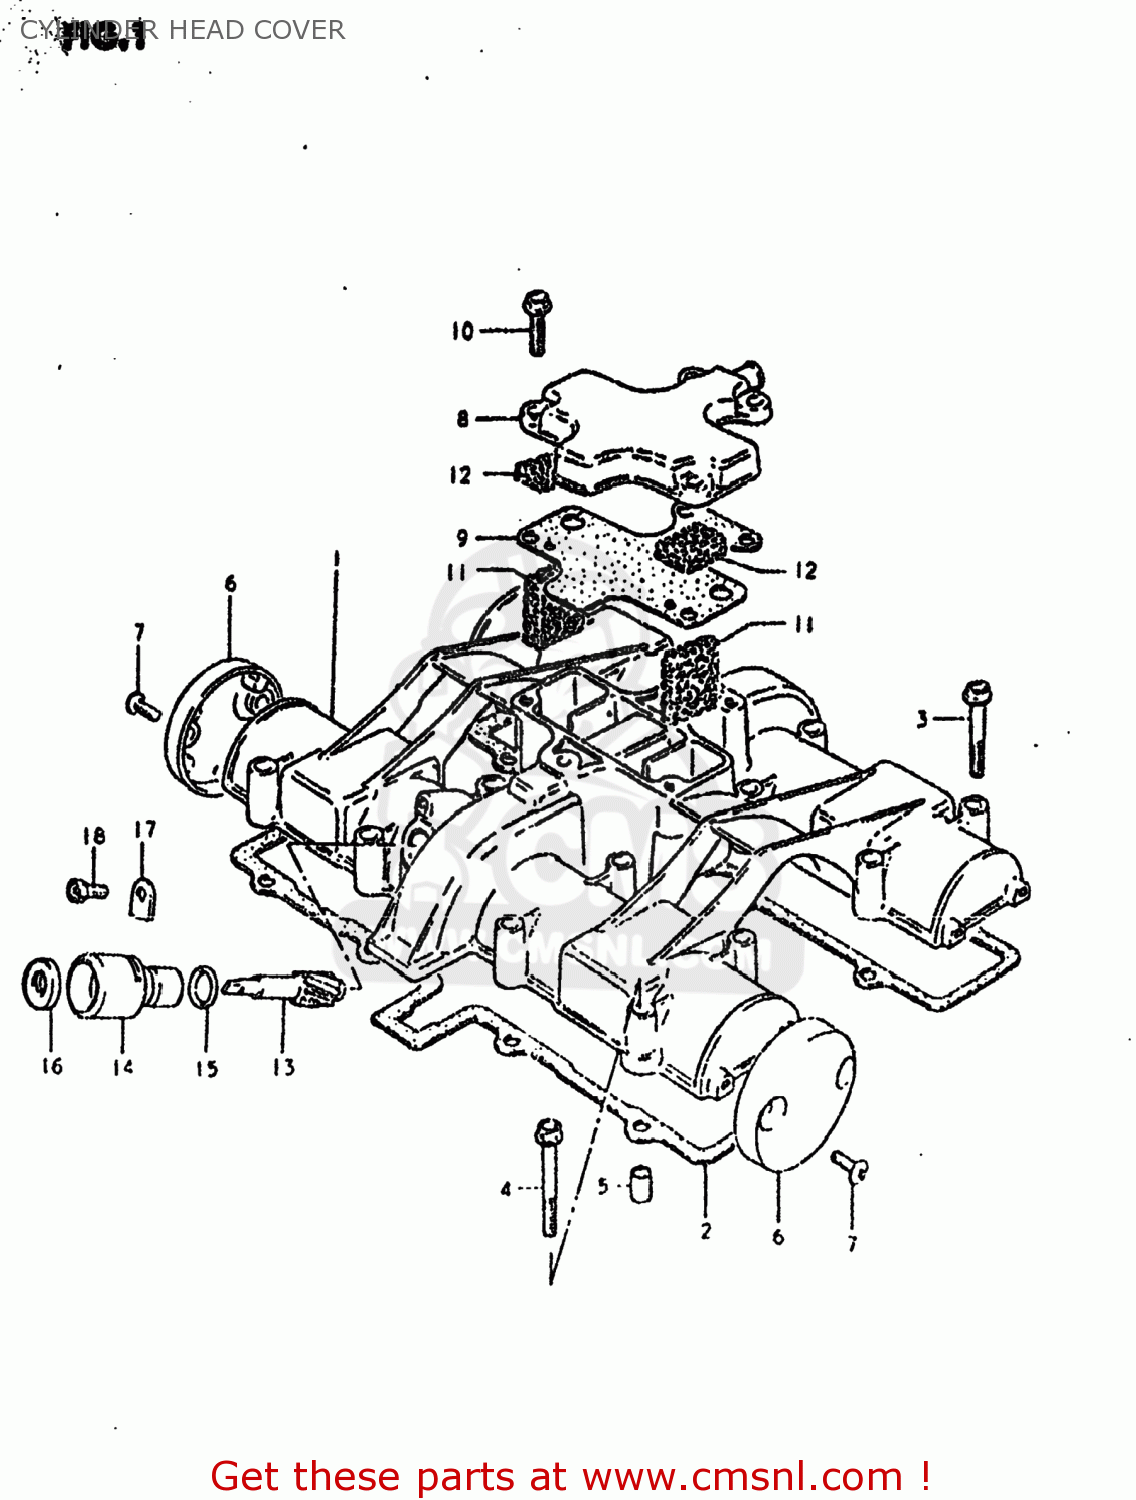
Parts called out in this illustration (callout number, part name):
1	COVER,CYLINDER HEAD
2	GASKET,CYLINDER HEAD COVER (MCA)
3	BOLT
4	BOLT,UNDER
5	PIN(6.2X8X11)
6	CAP,CYLINDER HEAD COVER
7	SCREW 5X12
8	COVER,BREATHER
9	GASKET (MCA)
10	BOLT,REAR
11	COVER,BREATHER
12	SEPARATOR,OIL BREATHER
13	GEAR,TACHOMETER DRIVEN
14	SLEEVE,TACHOMETER DRIVE
15	SEAL,TACHOMETER DRIVEN
16	SEAL,OIL(5X12X8)
17	PLATE,TACH DRIVE GEAR SLEEVE
18	SCREW(5X12)
